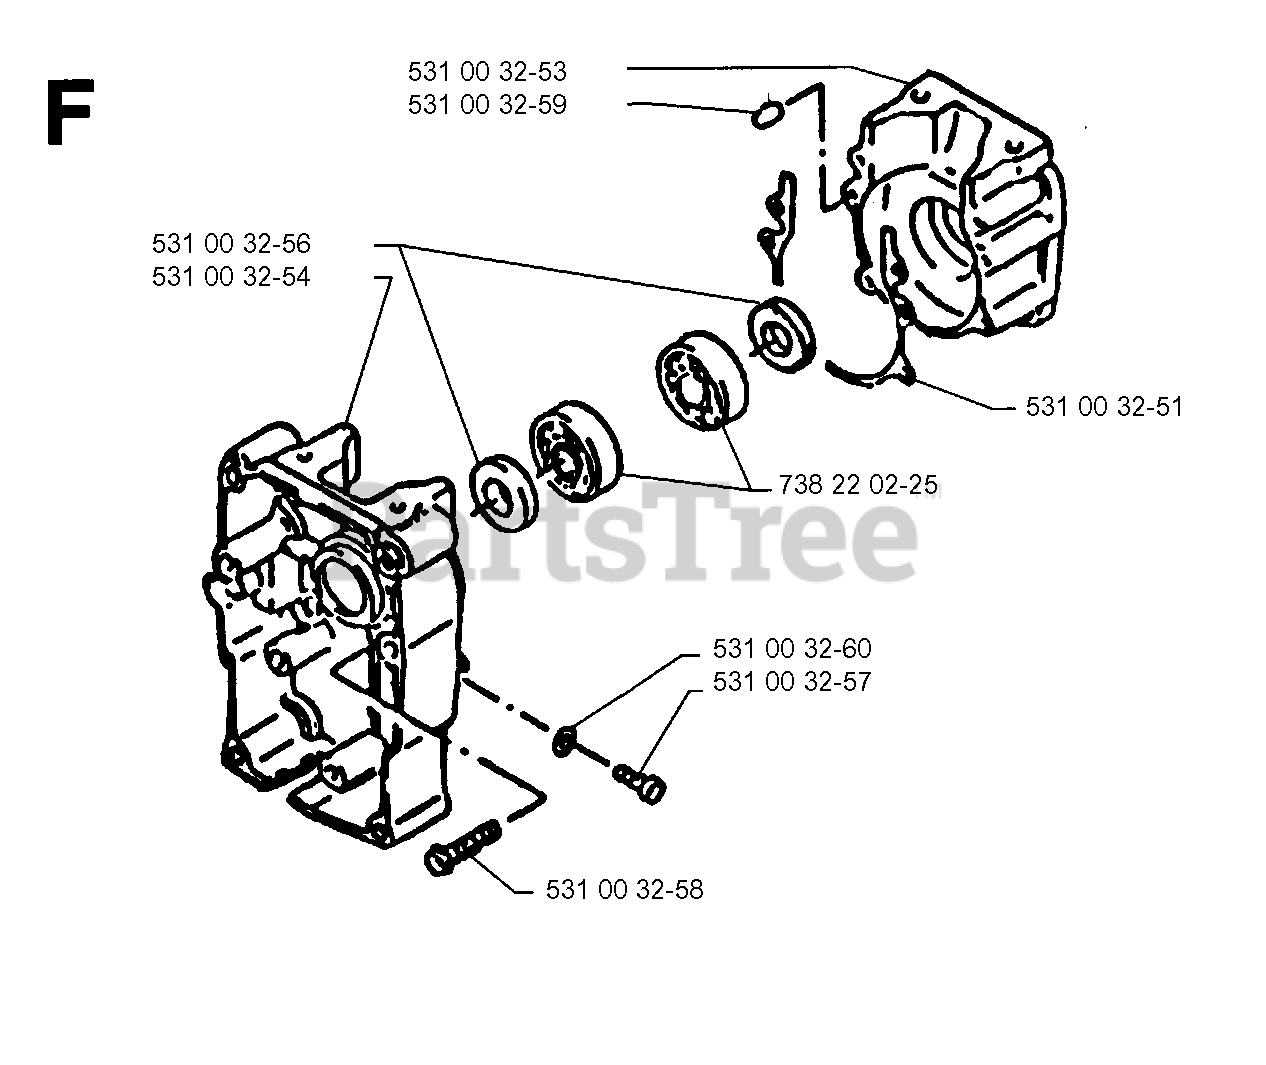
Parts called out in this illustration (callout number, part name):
1	RAIL, FRAME RH
2	DRAWBAR-GT
3	SIDE PANEL LH
4	NUT, CROWNLOCK 7/16-14 UNC
6	DASH VGT, LOWER
7	SCREW, THD CUT 1/4-20 X 1/2
8	SUPPORT, BATTERY
9	PAL NUT LT
14	HOOD ASM PNT
15	LENS
16	COVER ACCESS
17	SCREW
18	GRILLE.ASM.HUSQVARNA.YTGT
19	BOLT
20	BOLT, FIN HEX 3/8-16 X 1
21	NUT
22	PANEL ASM SD RH
23	SCREW 3/8-16 X 1/2
24	FOOTREST RH
25	LENS
27	NUT FIN HEX 1/4-20
28	FOOT REST LH
29	DASH SUPT YP
30	SADDLE.HYDRO.95
31	BRACKET SUPT 1-PC VGT STEERING
34	ENGINE SUPPORT BRKT
35	WASHER 11/32 X 11/16 X 16 GA.
36	BOLT, FIN HEX 5/16-18 X 3/4
37	FENDER
38	WASHER LOCK
39	FRONT AXLE BRACKET
40	BRACKET, SUPPORT AXLE/ENGINE
43	FRONT SUSPENSION BRKT LH
44	FRONT SUSPENSION BRKT RH
45	BRACKET SUSP RH
46	WASHER 9/32 X 3/4 X 16 GA.
47	SCREW
50	BRACKET, CHASSIS FRONT
52	NUT
54	NUT
56	BRACKET ASM, SUSP CHASSIS
58	FENDER BRKT
60	SCREW
63	WASHER 13/32 X 1 X 14 GA.
68	SCREW
70	BELT GUIDE
72	SCREW
74	SCREW
76	WELDNUT
79	SCREW, MACHINE #10-24 X 1/4
80	SPACER, SPLIT
82	NUT #10-24
84	MOWER STOP
86	BOLT, FIN HEX 7/16-14 UNC X 1
90	WASHER
91	RAIL, FRAME LH
92	PLATE, SILKSCREEN DASH
98	BRACKET CHASSIS
99	ROD ASM. BYPASS
100	PLUNGER CAP
101	SCREW THDROL. 3/8-16 X 1-3/4
102	RETAINER SPRING 1"
103	BRACKET LOCK BYPASS
106	SCREW THDROL. HEX HD ZINC MUR
107	LATCH.HOOD.
108	SNAP CAP LT
110	PIVOT ASM GRL/HD
112	NUT
114	BOLT, CARRIAGE 3/8-16 X 1-1/4
115	BUMPER ASM
116	BRACKET BUMPER
117	PLUG PLASTIC
118	WASHER
119	NUT
130	SCREW
131	BRACKET.SUPPORT.HOOD/PANEL.NLA
132	SCREW 10-24X3/8
136	SCREW
138	CUPHOLDER
139	BOLT, SHOULDER 5/16-18 TT
145	WASHER FLAT 13/32 X 7/8 X 16GA
151	SCREW 5/16-18 X 3/4
152	SCREW
153	NUT
154	BOLT HEX FIN 3/8-13 X 1
